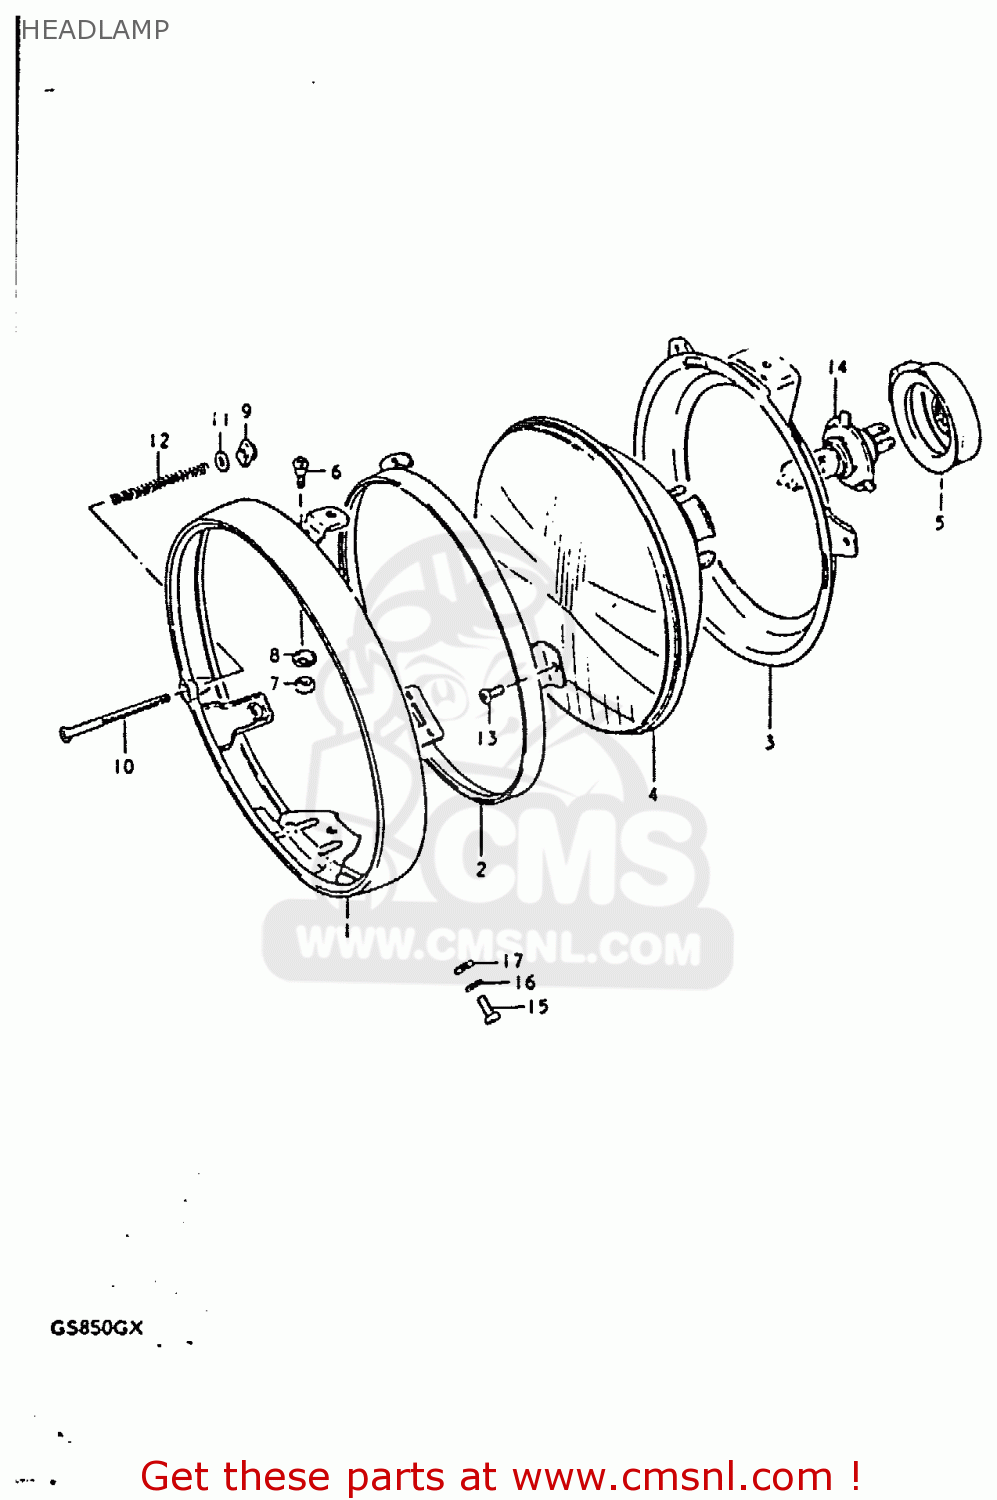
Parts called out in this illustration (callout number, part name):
1	RIM
2	RETAINER
3	RING,HEADLAMP UNIT
4	LAMP UNIT
5	COVER,HEADLAMP SOCKET
6	SCREW
7	NUT,ADJUSTING
8	SPACER
9	NUT
10	SCREW
11	WASHER
12	SPRING,HEADLAMP ADJUST
13	SCREW
14	BULB(12V60/55W,H4)
15	SCREW
16	WASHER,LOCK
17	WASHER
